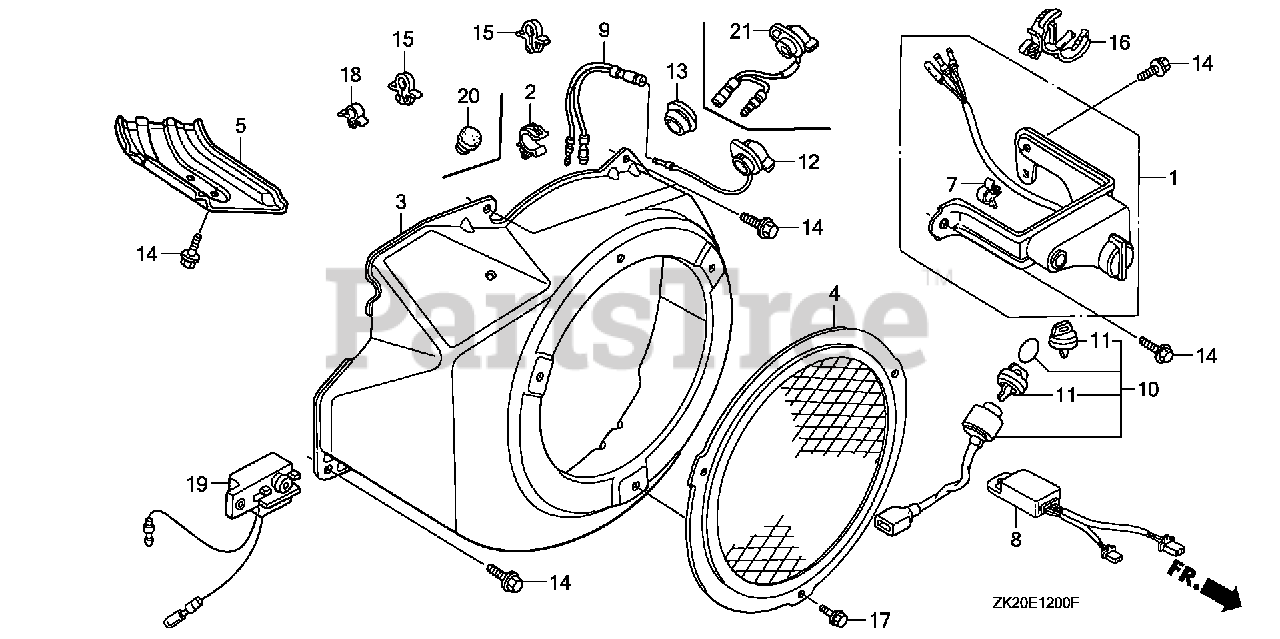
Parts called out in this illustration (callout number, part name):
2	CLIP, TUBE
3	COVER, FAN *NH1* (BLACK)
3	COVER, FAN *R280* (POWER RED)
9	SUB-HARNESS
12	SWITCH ASSY., ENGINE STOP
14	BOLT, FLANGE (6X12) (CT200)
16	CLIP, HARNESS
